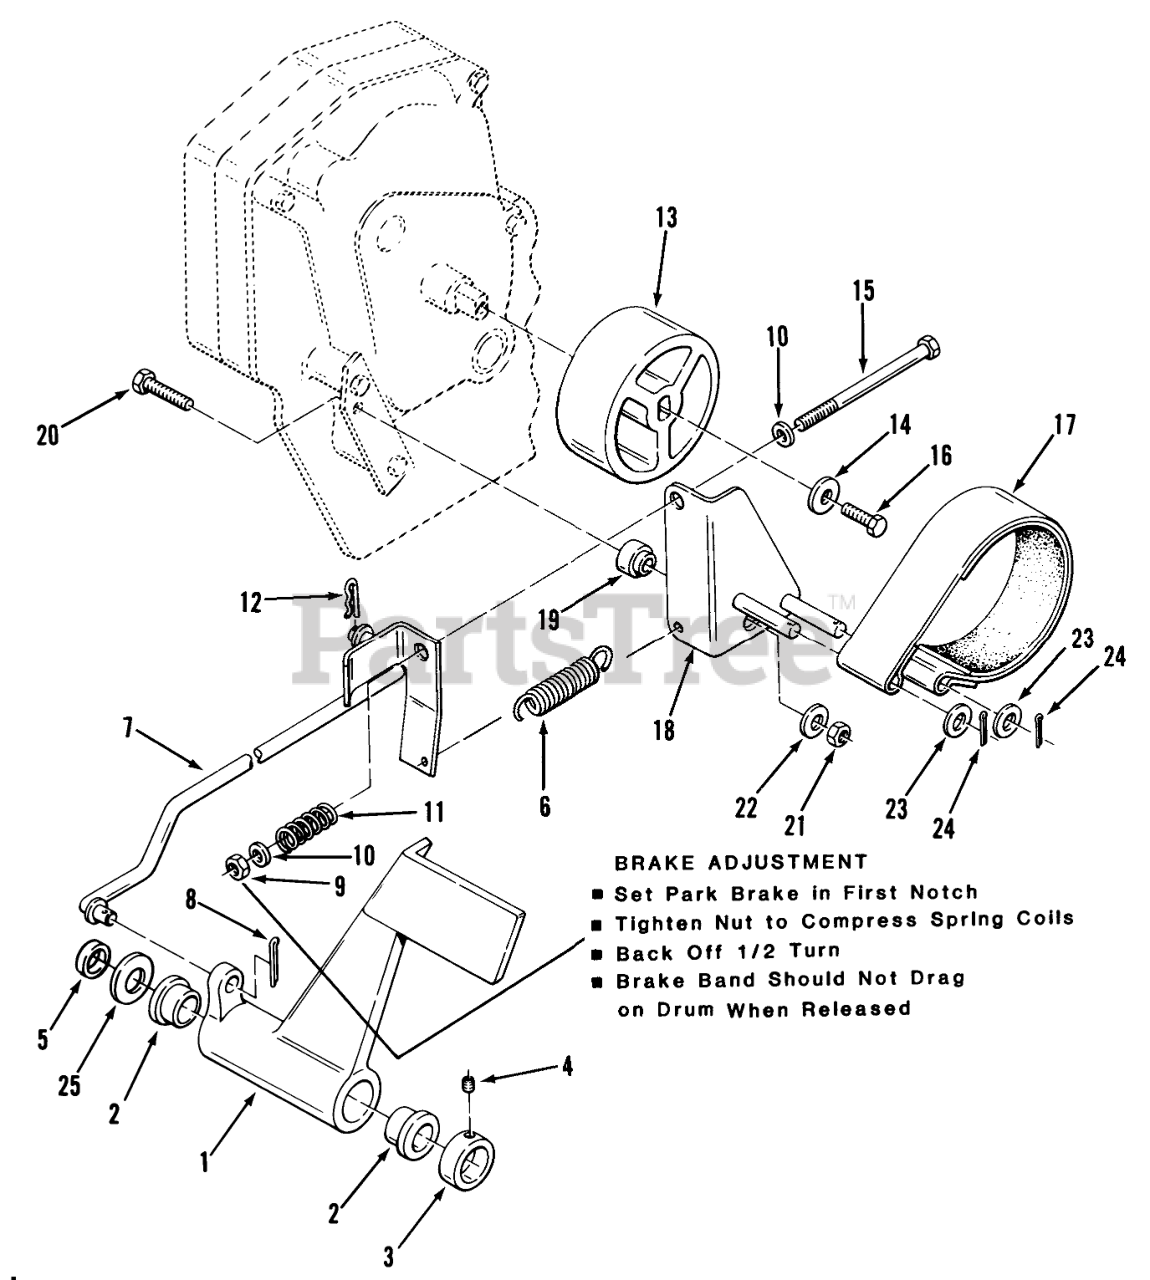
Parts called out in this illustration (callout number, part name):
1	PEDAL R
2	BUSHING
3	Collar
4	SCREW-SET
5	Spacer
6	SPRING
7	ASY BRAK RD WAR
9	NUT
10	Washer
11	SPRING-COMPRESSION
13	DRUM-BRAKE
14	WASHER
15	BOLT
16	BOLT
17	ASSY-BRAKE BAND
18	Brake Pivot Arm
19	BUSHING-BRAKE PIVOT
20	BOLT
21	Nut
22	Washer
23	Washer
24	Cotter Pin
